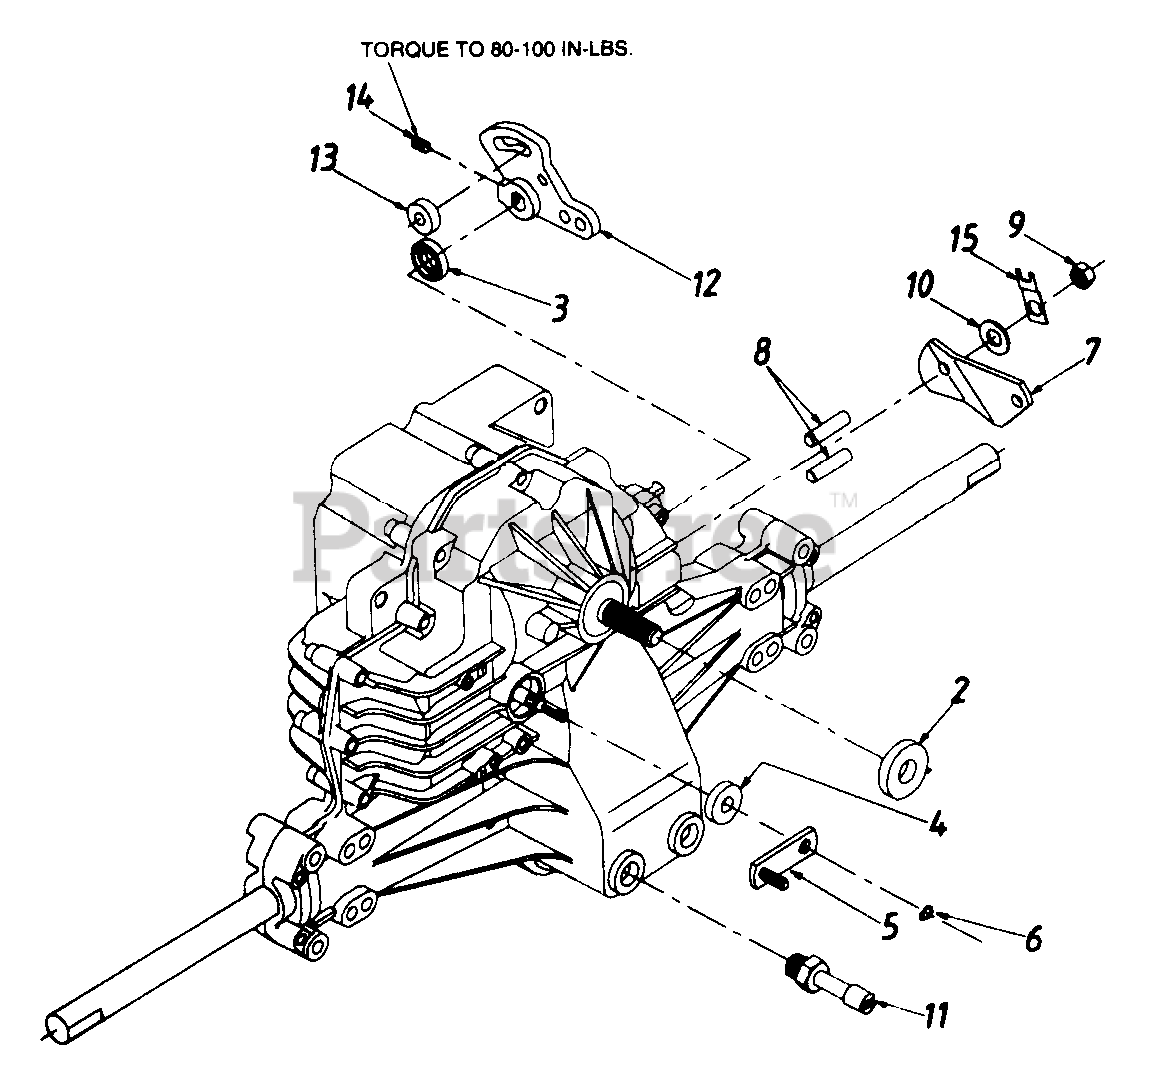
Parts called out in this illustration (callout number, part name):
4	Seal - Lip 10 X 25 X 7
5	Arm - Bypass
6	Ring - Retaining
7	Arm - Actuating
8	Pin - Actuating
9	Nut - Hex Lock 5/16-24 UNJC
10	Washer 7/16" x 7/8" x .060"
11	Breather Ass'y.
12	Arm - Control
13	Puck - Dampener
15	Strap, Locking
